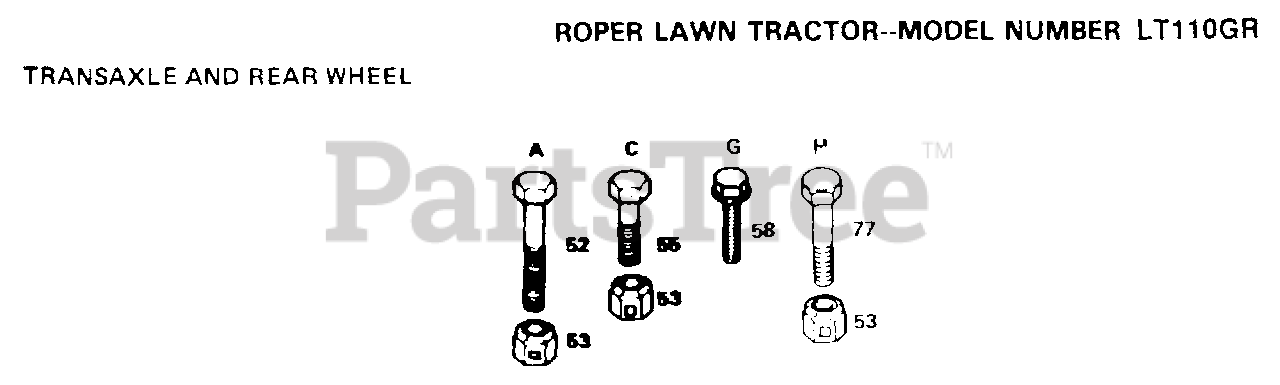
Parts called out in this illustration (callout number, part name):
52	BOLT
58	SCREW
77	BOLT
